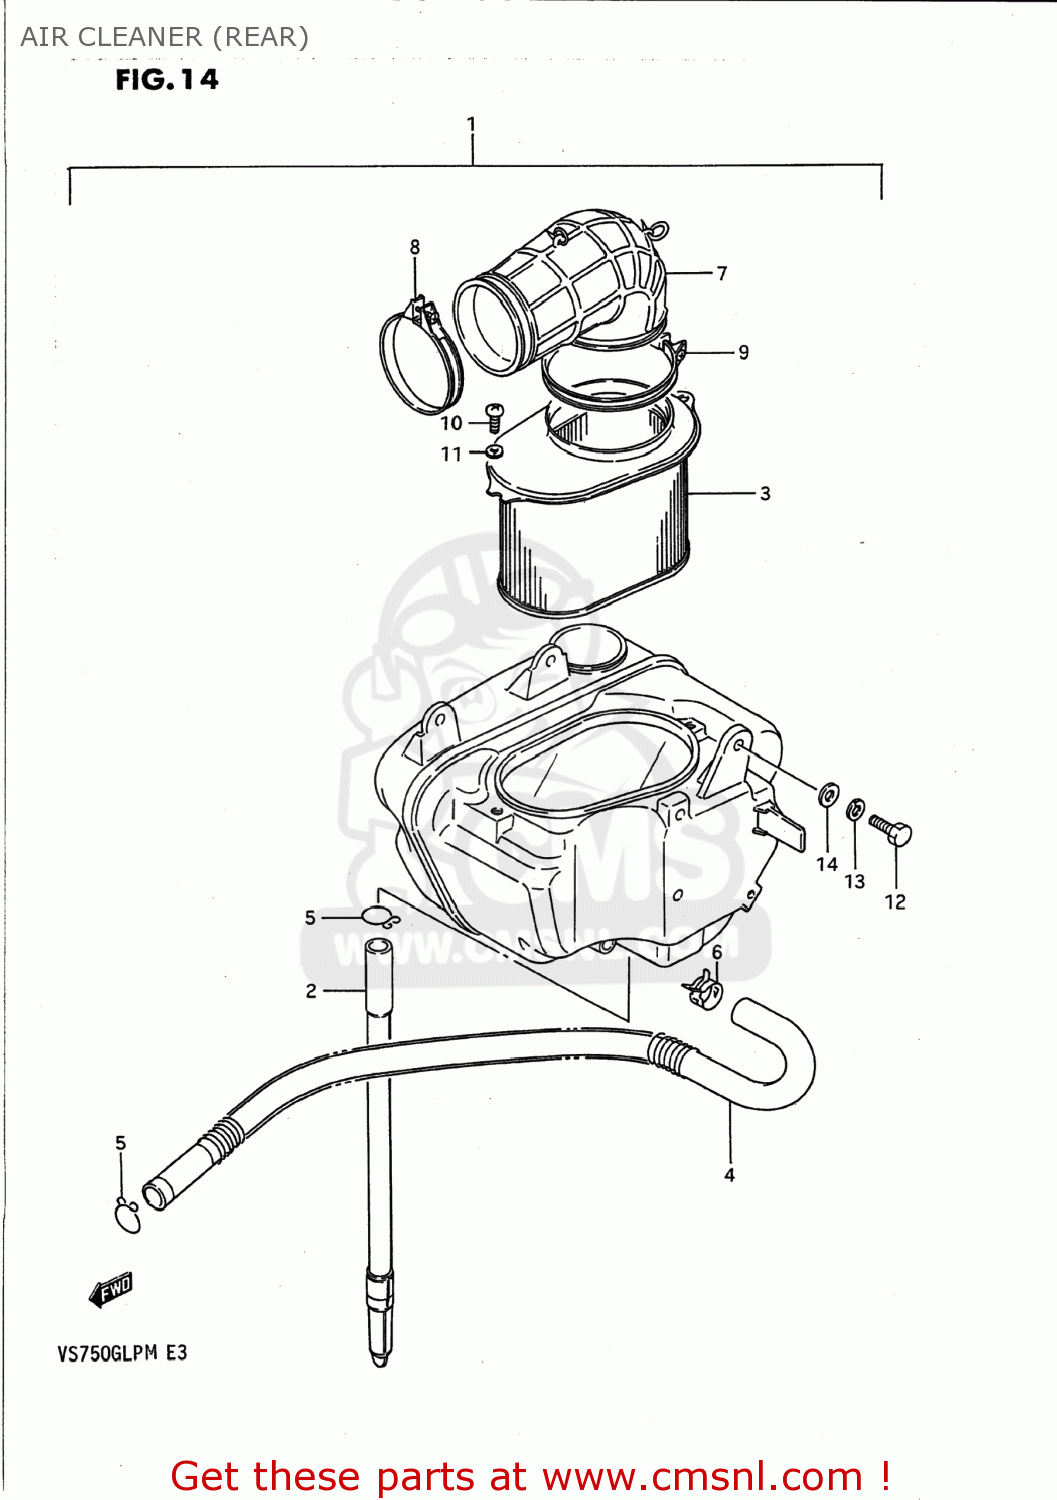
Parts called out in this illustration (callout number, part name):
1	CLEANER ASSEMBLY,AIR
2	DRAIN TUBE
3	FILTER,AIR CLEANER
4	TUBE SET,BREATHER
5	CLIP
6	CLIP
7	TUBE,AIR CLEANER OUTLET
8	CLAMP
9	CLAMP
10	SCREW
11	WASHER,LOCK
12	BOLT
13	WASHER,LOCK
14	WASHER(6.5X16X1.2)
